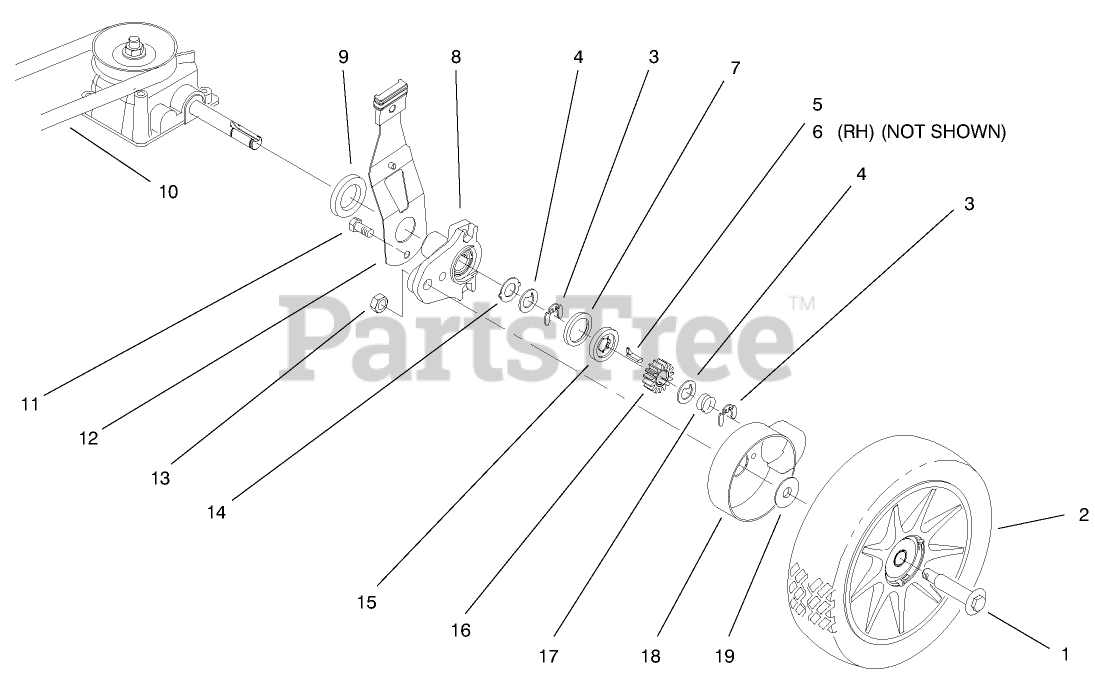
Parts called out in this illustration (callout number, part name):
1	BOLT-SHOULDER
2	WHEEL AND TIRE ASM
3	RING-RETAINING,CLIP
4	WASHER-THRUST, KEYED
5	KEY-ROCKING, LH
6	KEY-ROCKING, RH
7	RING-FRICTION
8	REAR HEIGHT ADJUSTMENT ARM ASM
9	SPACER-SHAFT, AXLE
11	SCREW-HWH
12	REAR SPRING ARM ASM
13	NUT-JAM, LOCKING
14	WASHER-ARM, PIVOT
15	WASHER-CLUTCH
16	GEAR-PINION
17	SPRING-COMPRESSION
18	COVER-WHEEL
19	WASHER-STEPPED
